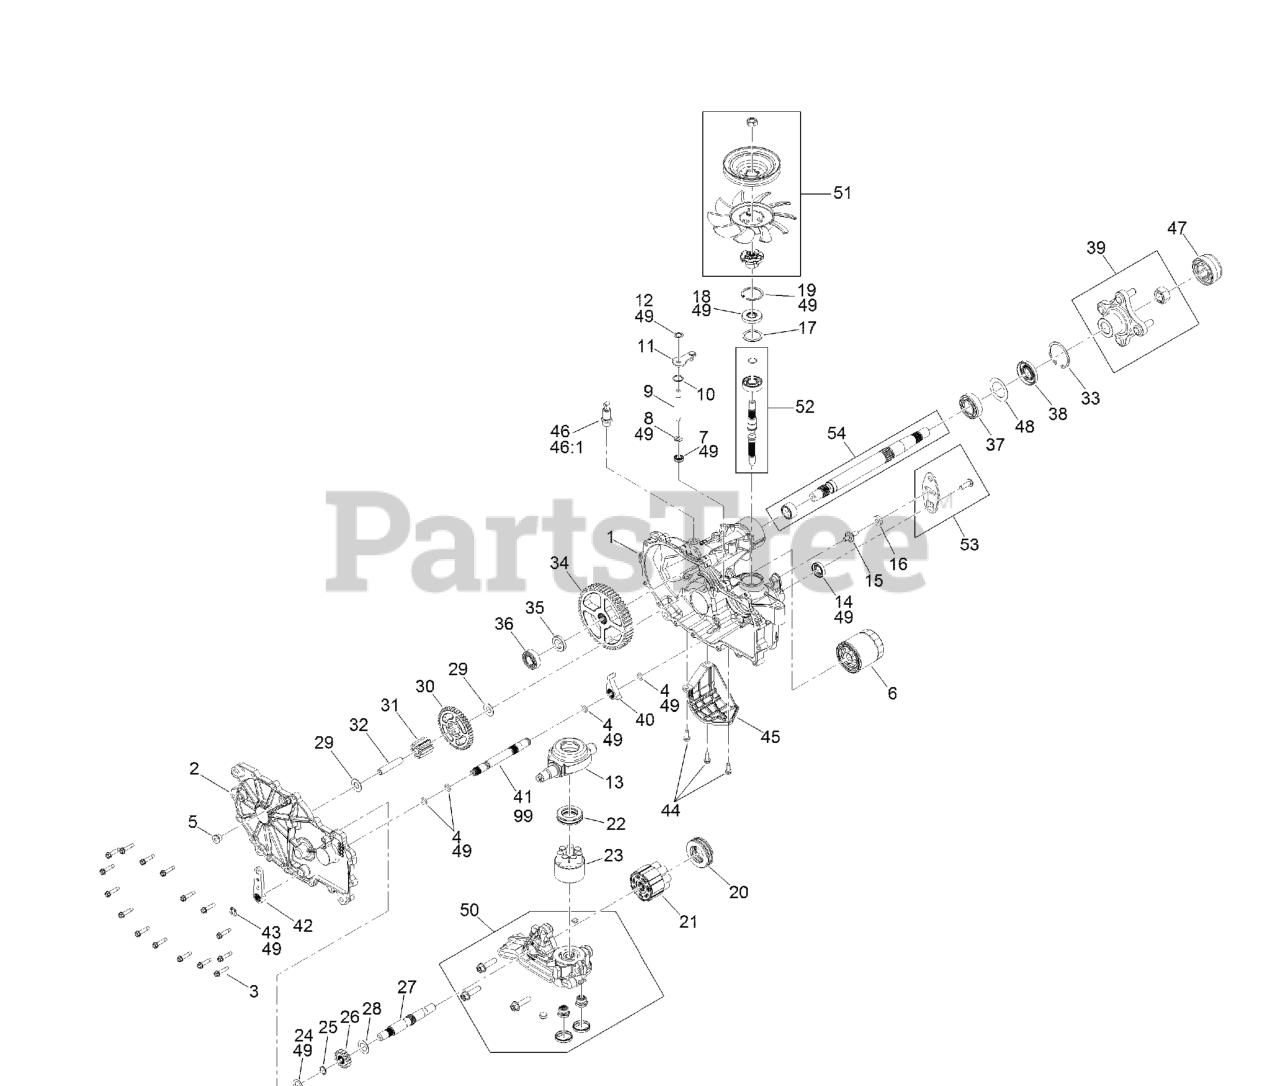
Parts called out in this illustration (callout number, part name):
1	MAIN HOUSING KIT
2	LH SIDE COVER KIT
3	SCREW-HHF
5	PLUG-THREAD, STRAIGHT
6	ELEMENT-OIL FILTER, HYD
7	SEAL-LIP
8	RING-RETAINING, EXTERNAL
9	ROD-BYPASS
10	RING-RETAINING, INTERNAL
11	ARM-BYPASS
12	RING-RETAINING, EXTERNAL
13	SWASHPLATE-TRUNNION
14	SEAL-LIP
16	PUCK-FRICTION
18	SEAL-LIP
19	RING-RETAINING
20	BEARING-THRUST
21	MOTOR CYLINDER BLOCK KIT
22	BEARING-THRUST
23	PUMP BLOCK ASM
24	WASHER-FLAT
25	RING-RETAINING
26	GEAR-16T
27	SHAFT-MOTOR
30	GEAR-43T
31	GEAR-11T
32	PIN-JACKSHAFT
33	RING-RETAINING
34	GEAR-54T
36	BEARING-BALL
37	BEARING-BALL
39	HUB KIT
40	PAWL-BRAKE
41	SHAFT-BRAKE, INBOARD
42	HANDLE-BRAKE
43	RING-RETAINING, EXT
45	GUARD-FILTER, LH
46	ADAPTER-STRAIGHT
46:1	O-RING
47	COVER-NUT, AXLE
49	SEAL KIT
50	CENTER SECTION KIT
51	FAN PULLEY KIT
52	INPUT SHAFT KIT
53	CONTROL ARM KIT
54	AXLE SHAFT KIT
99	BRAKE SHAFT SEAL KIT
